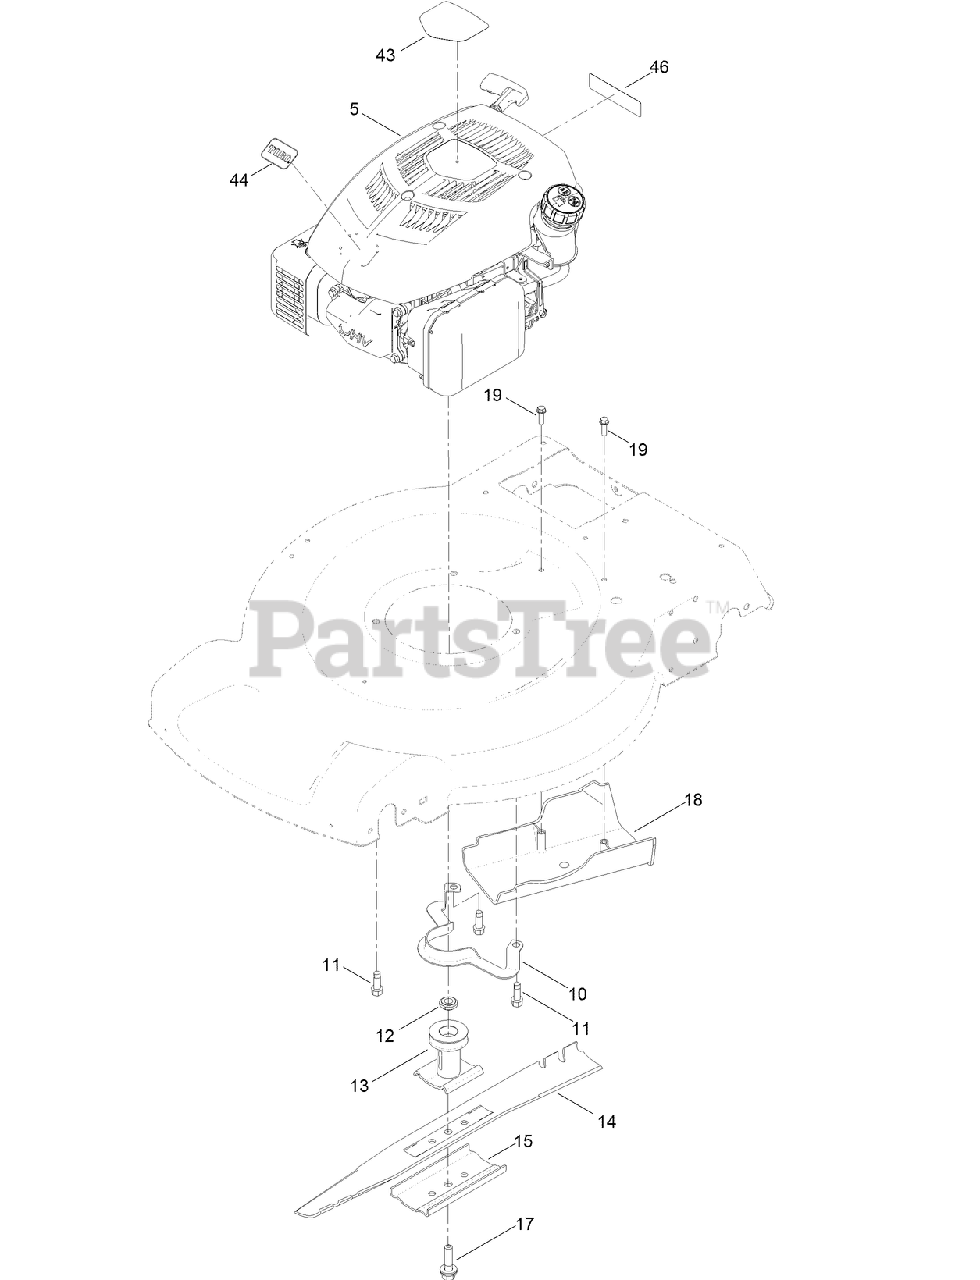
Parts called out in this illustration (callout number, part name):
5	ENGINE-1P65F-2
10	GUIDE-BELT
11	SCREW-TAPTITE
12	SPACER-DRIVER
13	DRIVER-BLADE
14	BLADE-22 INCH
15	SUPPORT-BLADE
17	BOLT-BLADE
18	COVER-BELT
19	SCREW-HWH
43	DECAL-SHROUD
46	DECAL-ARRESTER, SPARK
